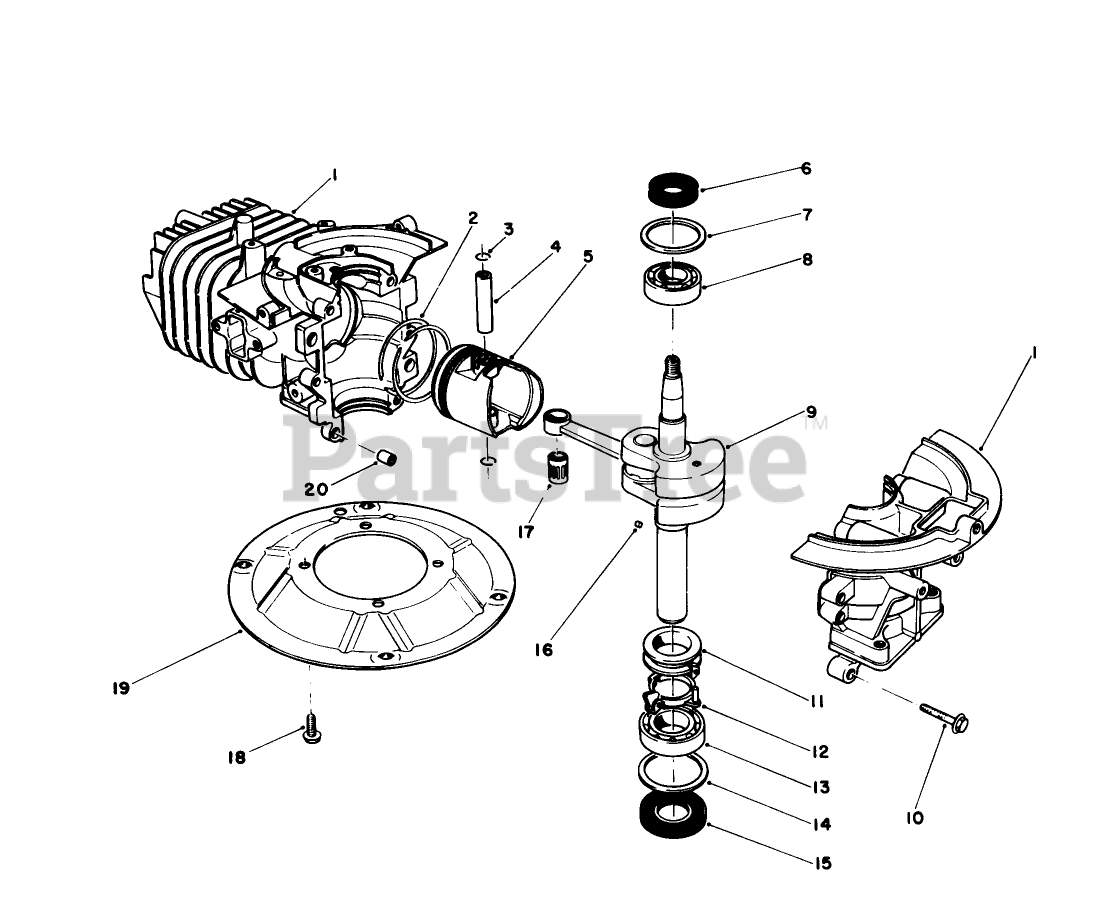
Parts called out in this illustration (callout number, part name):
2	RING SET
4	PIN-PISTON
6	OIL SEAL
7	WASHER-UPPER
8	BEARING-UPPER
11	SPACER
12	BRACKET
13	LOWER BRG
14	WASHER-LOWER
15	SEAL-OIL
17	BEARING
19	PLATE-MOUNTING
